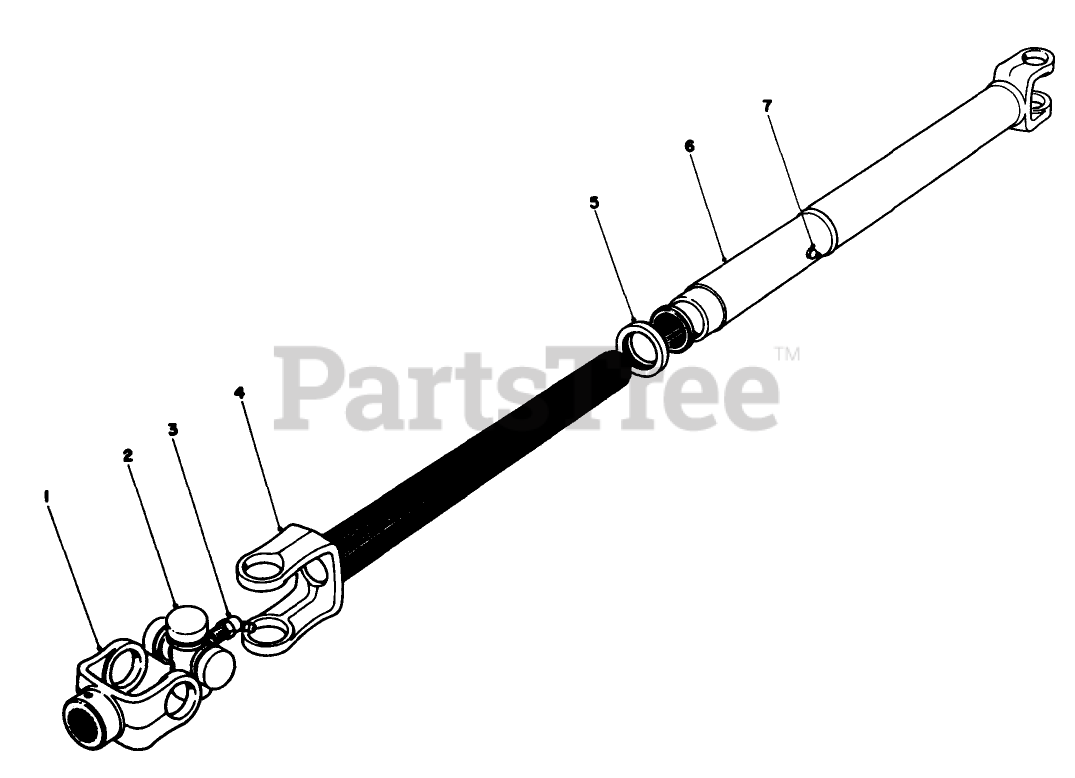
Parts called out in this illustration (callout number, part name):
1	End Yoke
2	U Joint Kit
3	Grease Fitting
4	Slip Yoke Shaft
5	DUST CAP ASM
6	Slip Yoke Tube
7	LUBE FITTING (21-3090
